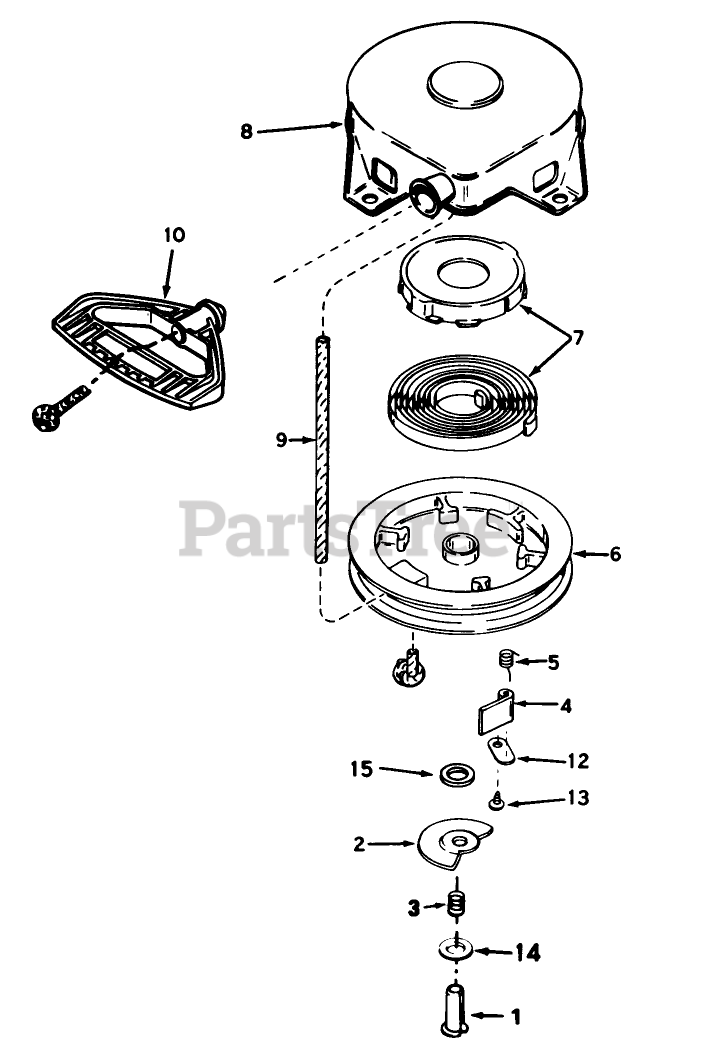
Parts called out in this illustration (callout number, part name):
1	Pin, Spring (Incl. Ref. #7)
2	Washer
3	Brake Spring
4	Dog-Starter
5	Spring-Dog
6	Pulley
7	Spring Keeper Assy
8	Housing-Starter
9	Rope-Starter
10	Handle-Starter, Mitten Grip
12	Retainer-Dog
13	Screw
14	Washer
15	Washer
